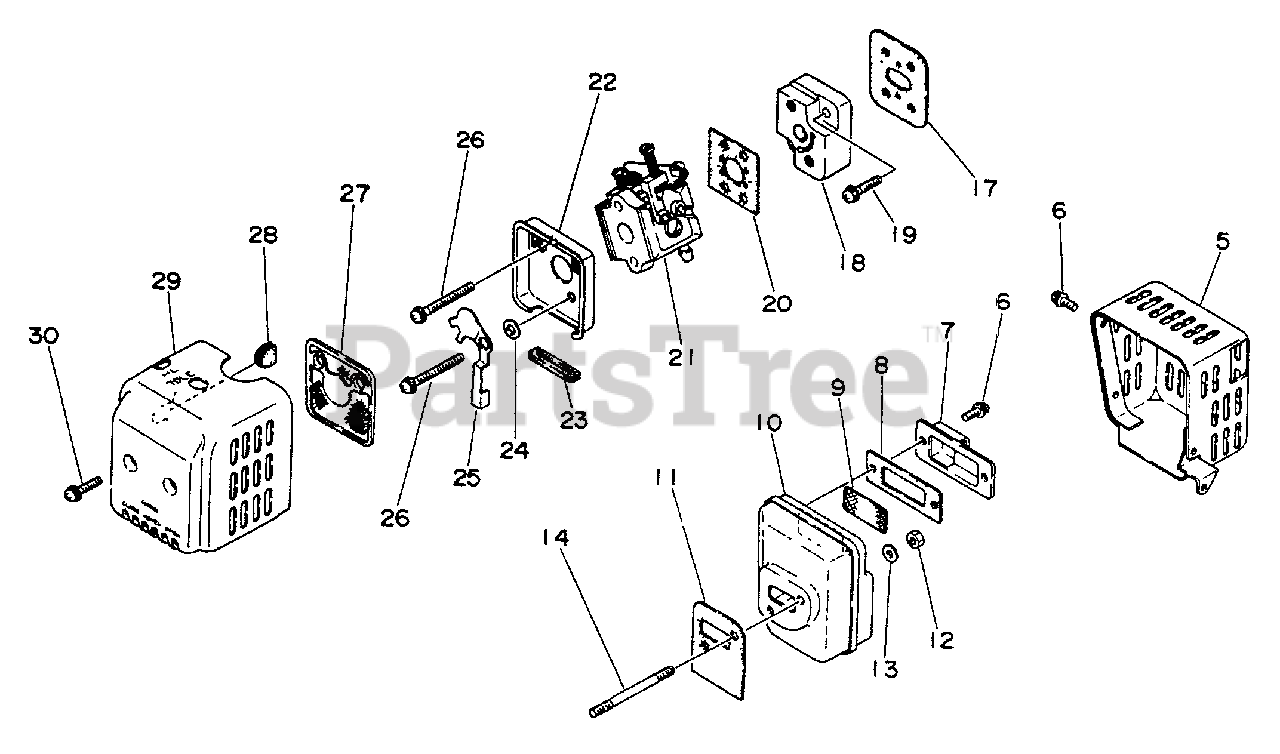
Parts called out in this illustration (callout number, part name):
5	COVER, EXHAUST
6	SCREW - 4X10
7	GUIDE, EXHAUST
8	GASKET, EXHAUST
9	SCREEN, SPARK ARRESTOR
10	MUFFLER
11	GASKET, EXHAUST
12	LOCKNUT - 5
13	WASHER - 5
17	GASKET, INTAKE
18	INSULATOR, INTAKE
19	SCREW - 5X20
20	GASKET, INTAKE
21	CARBURETOR WA-138A
21	CARBURETOR WA-143
22	CASE, AIR FILTER
24	WASHER - 5
25	SHUTTER, CHOKE
26	SCREW - 5X40
27	FILTER, AIR
28	PLUG
29	COVER, AIR FILTER
30	SCREW - 4X18
